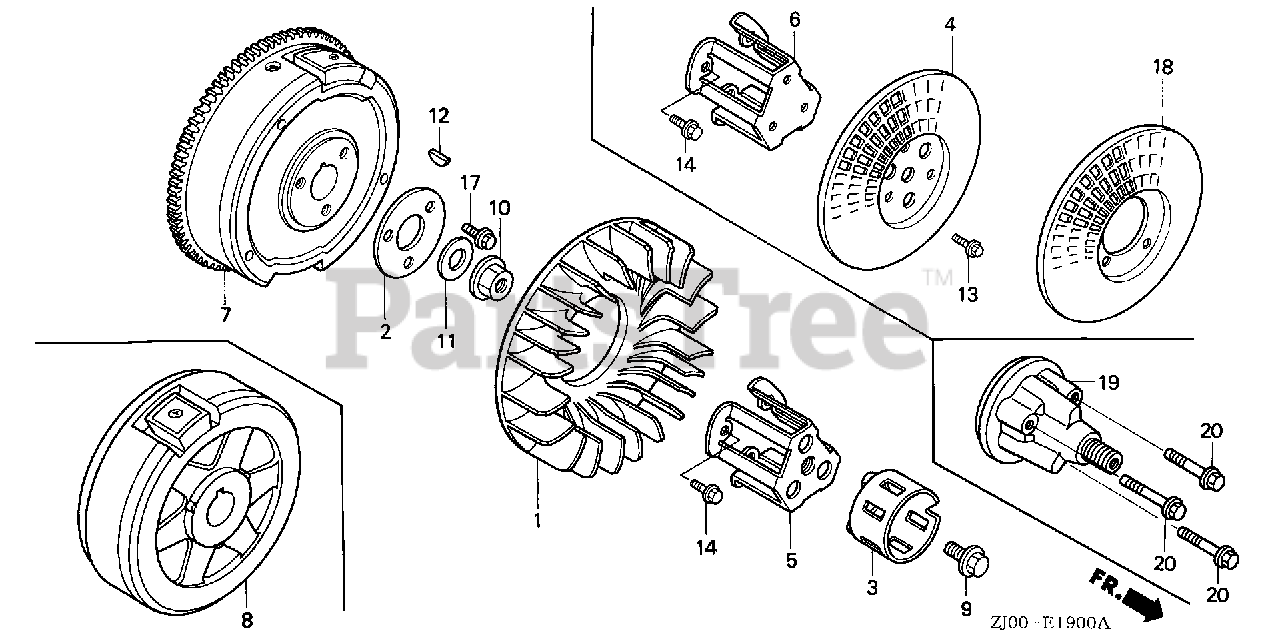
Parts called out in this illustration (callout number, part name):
1	FAN, COOLING
3	PULLEY, STARTER
4	GRID, SCREEN (P.T.O.)
5	SPACER, STARTER PULLEY MOUNTING
6	HOLDER, SCREEN GRID
9	BOLT, UBS (12X28)
10	NUT, FLANGE (20MM)
11	WASHER (20MM)
12	KEY, SPECIAL WOODRUFF (25X18)
14	BOLT, FLANGE (8X16)
17	BOLT, FLANGE (8X16)
18	GRID, SCREEN (P.T.O.)
